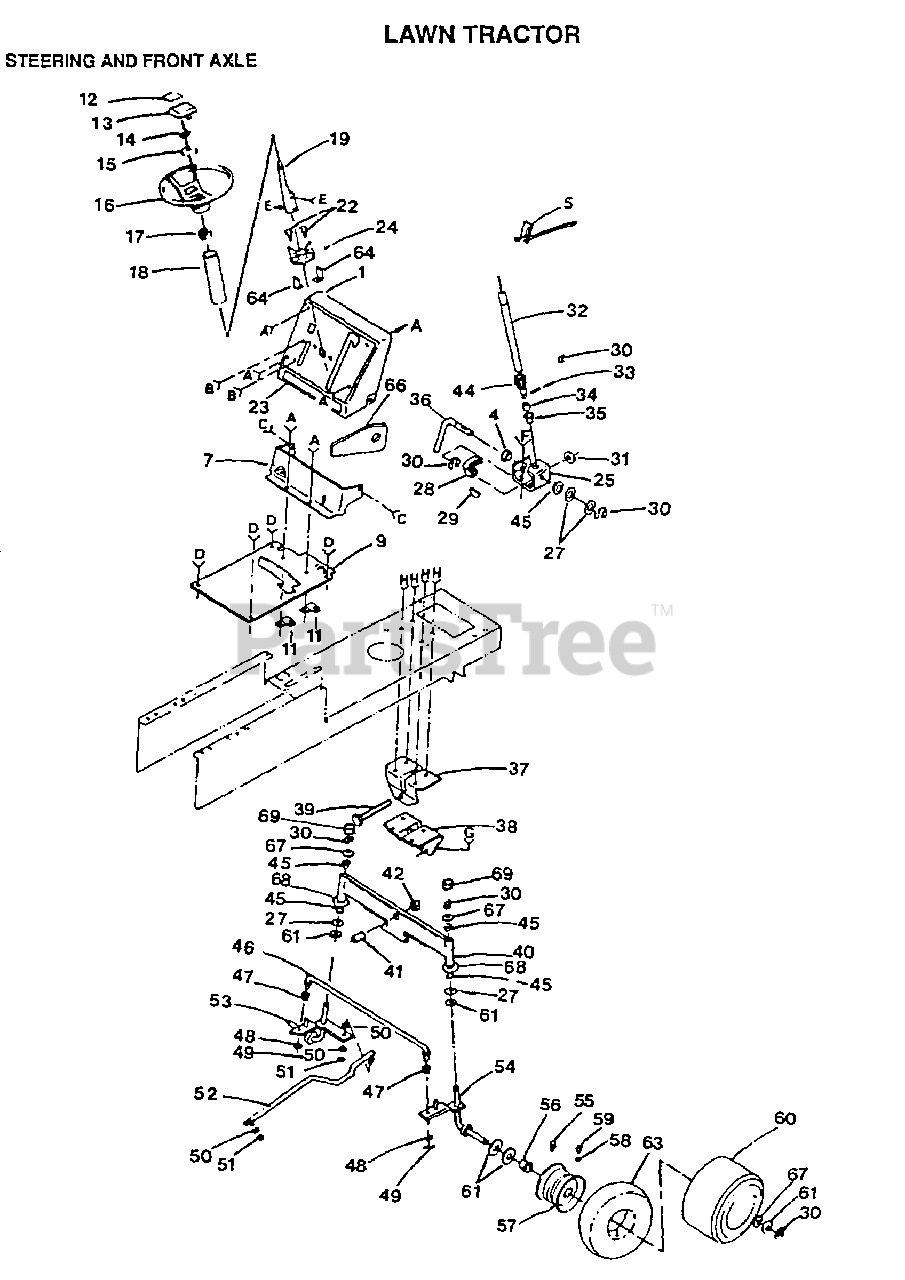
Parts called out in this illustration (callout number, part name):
4	NYLINER T
7	DASH-LOWER LT
11	CLIP T
13	INSERT-WHEEL LT
15	WASHER
17	ADAPTER LT
24	BUSHING T
27	WASHER .T
28	GEAR.SECTOR.HYT
29	KEY-WOODRUFF LT
30	RING
32	STEERING SHAFT T
34	SHAFT SPACER LT
35	BUSHING
36	ROD STEERING T
37	SUPPORT-SADDL T
38	SUPPORT.SADDLE.FT
39	BOLT LT
41	BEARING
42	"NUT-LOC,FLANGE LT"
44	GEAR PINION T
45	COL. SRTG. BEAR.
48	WASHER
49	COTTER PIN
50	LOCKWASHER
52	LINK-DRAG LT
53	SPINDLE-LH LT
55	FITTING LT
56	"FLANGE, BEARING"
58	VALVE CAP
59	VALVE STEM LT
61	WASHER
63	TUBE.5.3/4.5/6
64	RETAINER T
67	WASHER
68	WASHER
69	CAP
